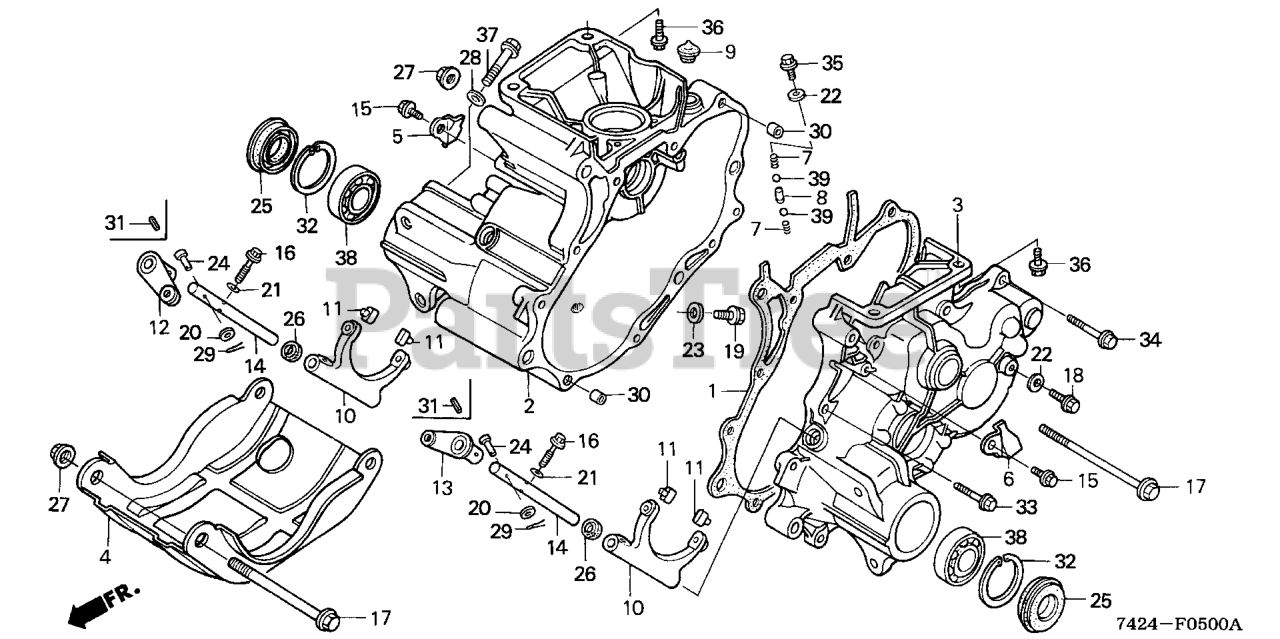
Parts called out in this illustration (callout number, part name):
1	GASKET, TRANSMISSION
2	CASE, R. TRANSMISSION
3	CASE, L. TRANSMISSION
4	PROTECTOR, TRANSMISSION CASE
5	PLATE, R. SIDE CLUTCH
6	PLATE, L. SIDE CLUTCH
7	SPRING, BALL SETTING
8	PIECE, INTERLOCK
9	CAP, TRANS OIL
10	FORK, SIDE CLUTCH
12	ARM, R. SIDE CLUTCH
13	ARM, L. SIDE CLUTCH
14	SHAFT, SIDE CLUTCH ARM
15	BOLT, FLANGE (6X12) (CT200)
16	BOLT, SPECIAL (6X21)
17	BOLT, ALTERNATOR
18	BOLT, FLANGE (8X16)
19	BOLT, DRAIN PLUG
20	WASHER (10MM)
21	WASHER, CONICAL SPRING (6MM) Use up to Frame SN 3500085.
22	WASHER, SEALING (8MM)
23	WASHER, DRAIN PLUG (10.2MM)
24	PIN, AUXILIARY CHANGE LEVER
25	OIL SEAL (25X52X9)
26	OIL SEAL (12X18X4.2)
27	NUT, FLANGE (10MM)
28	WASHER, PLAIN (10MM)
29	PIN, COTTER (2.0X12)
30	PIN A, DOWEL (8X14)
32	CIRCLIP (INNER) (52MM)
33	BOLT, FLANGE (6X32)
34	BOLT, FLANGE (6X40)
35	BOLT, FLANGE (8X16) Use from Engine SN 1000016.
36	BOLT, FLANGE (8X28)
37	BOLT, FLANGE (10X65)
38	BEARING, RADIAL BALL (6205)
39	BALL, STEEL (#8) (1/4)
